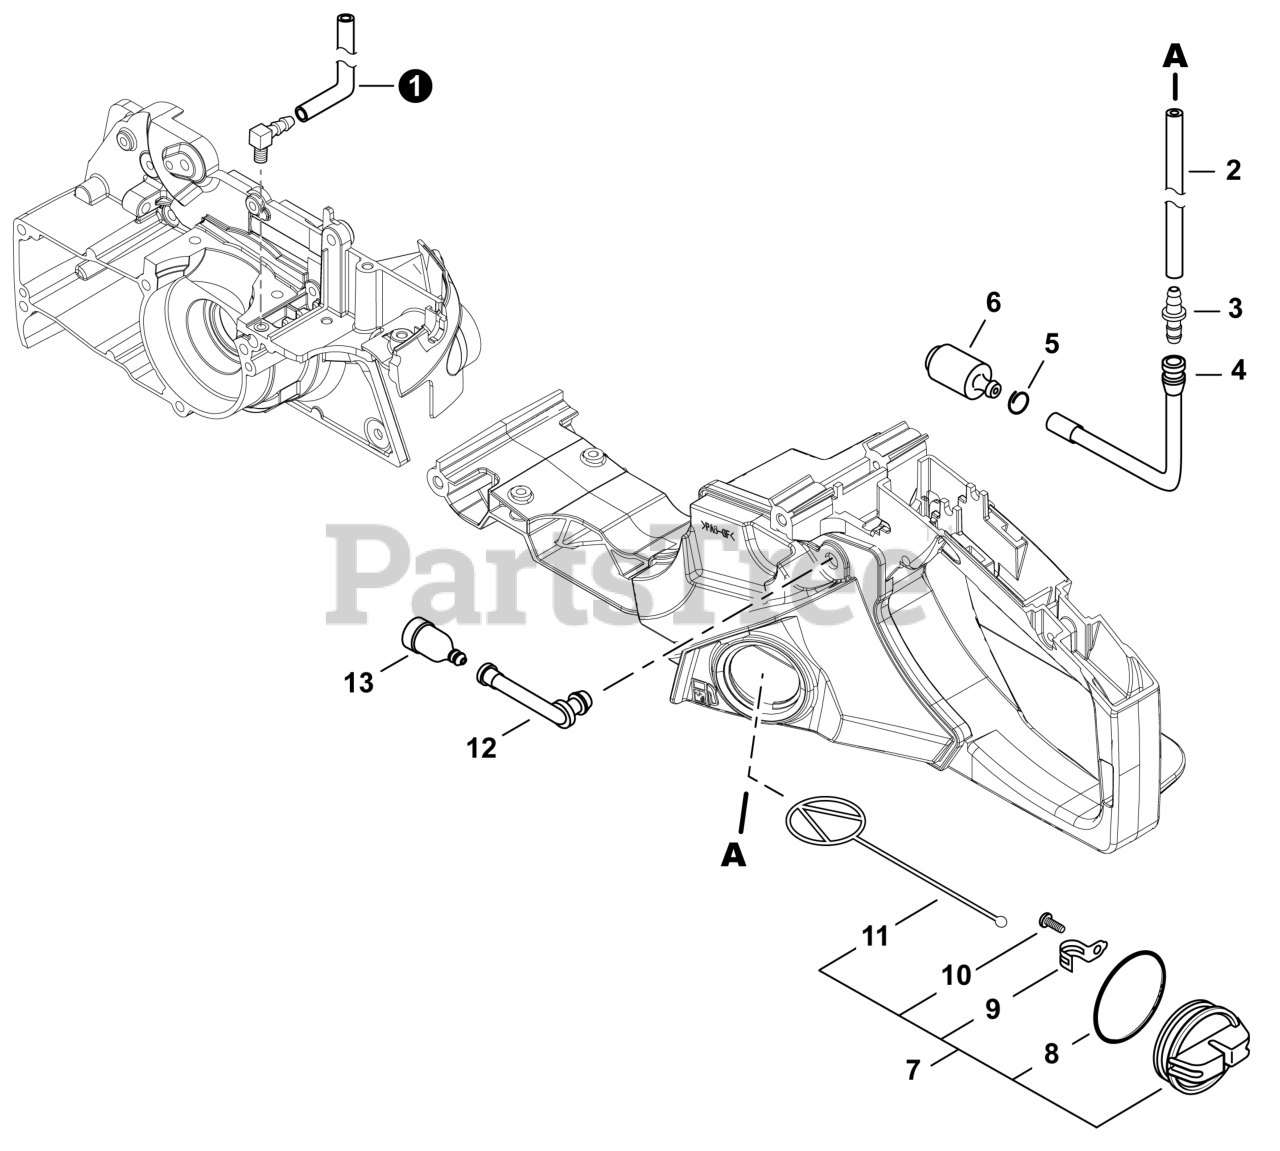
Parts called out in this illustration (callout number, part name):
1	PIPE, PULSE
2	PIPE, FUEL - 3*6*75 2020
3	CONNECTOR, PIPE
4	PIPE, FUEL
5	CLIP Ø6
6	FILTER, FUEL
7	CAP ASSY, FUEL
8	O-RING 29
9	RETAINER, CONNECTOR
10	PIPE, FUEL VENT, CS-490/501
11	VENT ASSY
12	TUNE-UP KIT - YOUCANT
